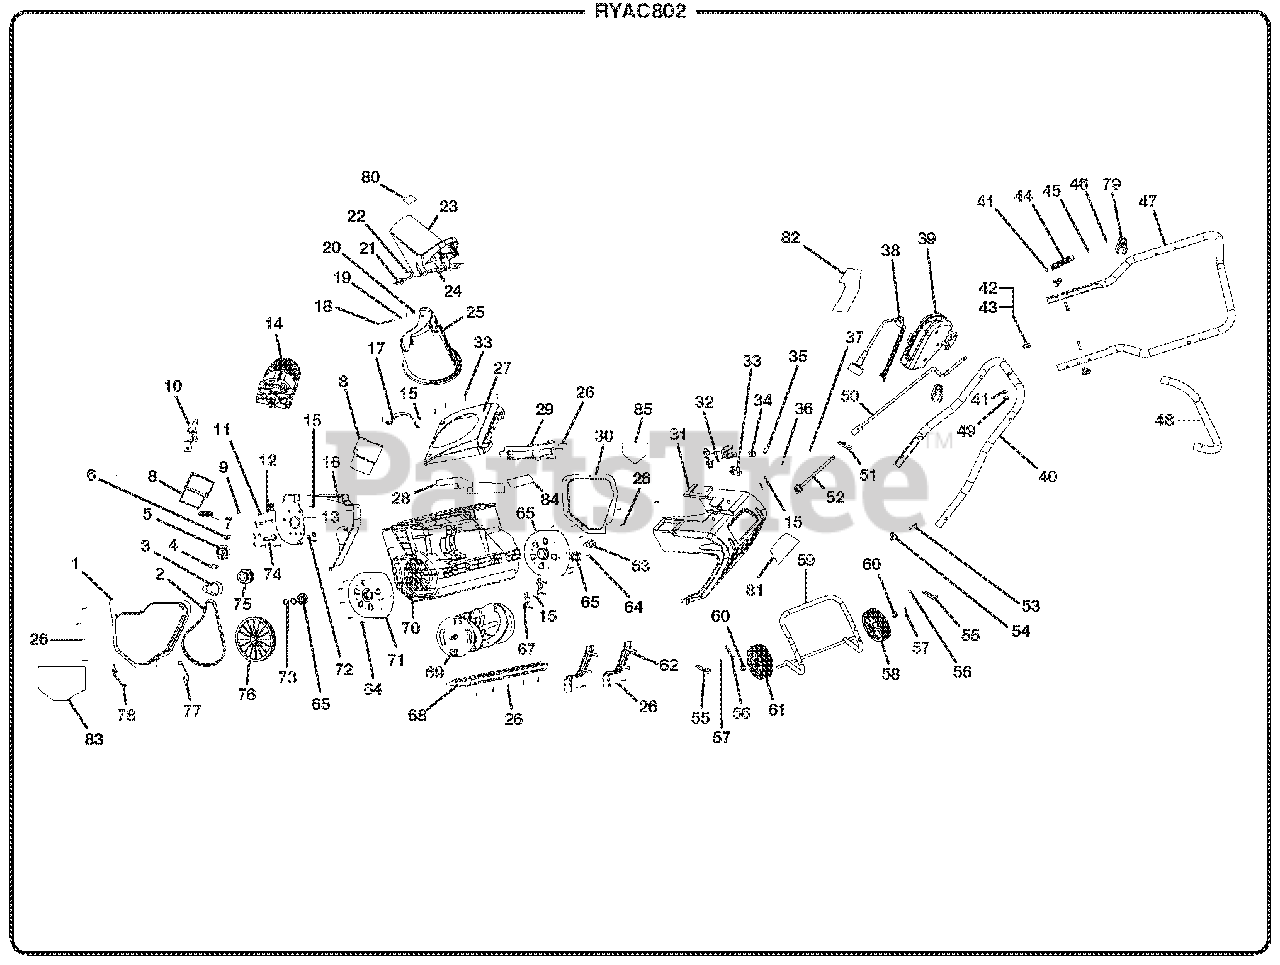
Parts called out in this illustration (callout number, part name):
1	Side Plate (Left)
2	Belt (Large)
3	Belt (Small)
4	Shaft (Tension Wheel)
5	Bearing (5202)
11	Bolt (M5 x 15 mm)
12	Washer (M5)
13	Motor Support Bracket
14	Motor Assembly
15	Screw (M4 x 16 mm)
18	Bolt (M3.5 x 110 mm)
19	Washer (M3.5)
22	Washer (M6)
24	Bolt (M6 x 22 mm)
25	Discharge Chute
26	Screw (M4.8 x 12 mm)
27	Outlet Cover
28	Water Holder
29	Inlet Cover
30	Side Cover (Right)
31	Rear Housing
32	Rotating Board
36	Screw (M4 x 30 mm)
39	Switch Box.
40	Handle (Middle)
41	Washer (M8)
43	Axle Rubber
45	Washer (M5)
47	Handle (Upper)
53	Bolt (M8 x 50 mm)
57	Washer (ID13.5 x 1.5t)
58	Wheel (Right)
59	Lower Handle
61	Wheel (Left)
62	Bracket (Front Housing)
64	Screw (M4.8 x 8 mm)
65	Bearing (6002-RS)
66	Support (Right)
70	Front Cover
71	Support (Left)
73	Washer (OD24 x ID15.4 x 1.7t)
75	Small Pulley
80	Chute Icon Label
81	Data/Warning Label
82	Starting Instructions/ Logo Label
83	Performance/Logo Label
84	Logo Label
85	Danger Label (No Hands/Feet)
